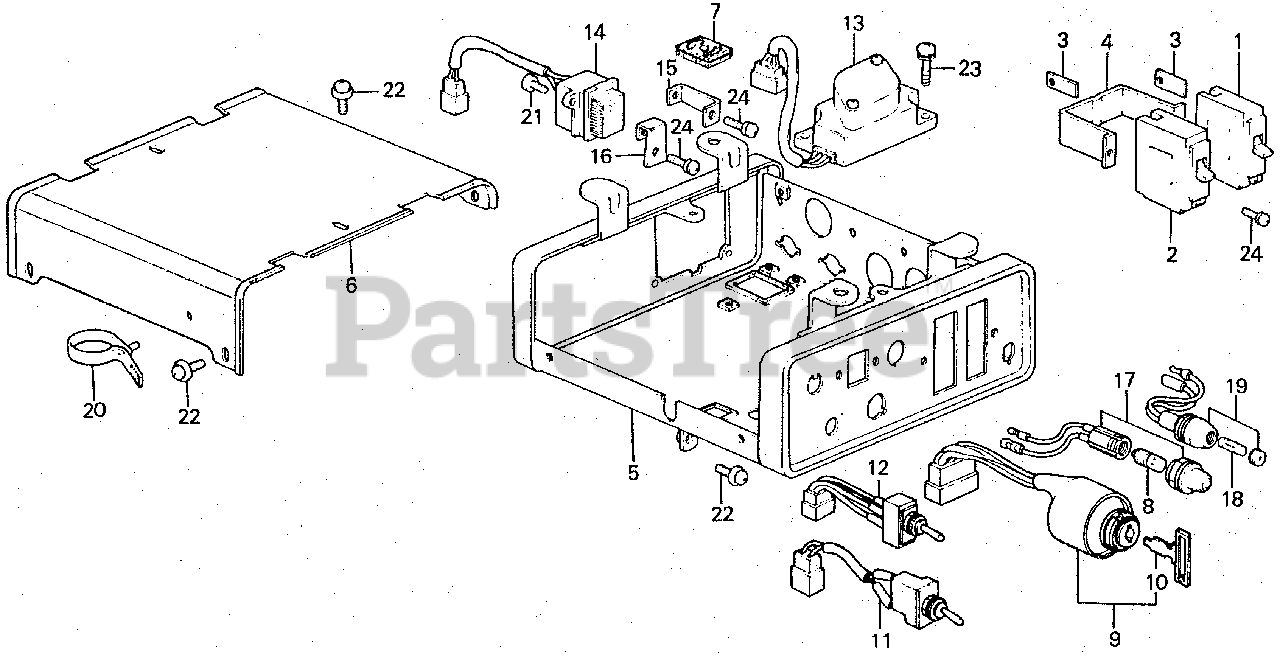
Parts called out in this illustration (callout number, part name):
1	BREAKER, CIRCUIT (18A) (NOT AVAILABLE)
2	BREAKER, CIRCUIT (37A)
3	TERMINAL, BREAKER
4	SUPPORT, BREAKER (NOT AVAILABLE)
5	BOX, CONTROL *R8* (BRIGHT RED)
6	COVER, CONTROL BOX (UPPER) *R8* (BRIGHT RED)
6	COVER, BOX (UPPER) *R8* (BRIGHT RED)
7	GROMMET, REMOTE CONTROL
8	BULB, DASH (24V-2W)
9	SWITCH ASSY., COMBINATION (NOT AVAILABLE)
10	KEY
11	SWITCH ASSY., IDLE CONTROL (NOT AVAILABLE)
12	SWITCH ASSY., CONTROL
13	CONTROL UNIT (NOT AVAILABLE)
14	METER, FREQUENCY (NOT AVAILABLE)
15	HOLDER A, FREQUENCY METER
16	HOLDER B, FREQUENCY METER
17	SOCKET ASSY., PILOT LAMP
18	FUSE (15A)
19	HOLDER ASSY., FUSE
20	STRAP B, CABLE (125MM) (BLUE)
21	SCREW, PAN (3X8)
22	SCREW-WASHER (5X12)
23	SCREW-WASHER (6X16)
24	SCREW-WASHER (4X12)
